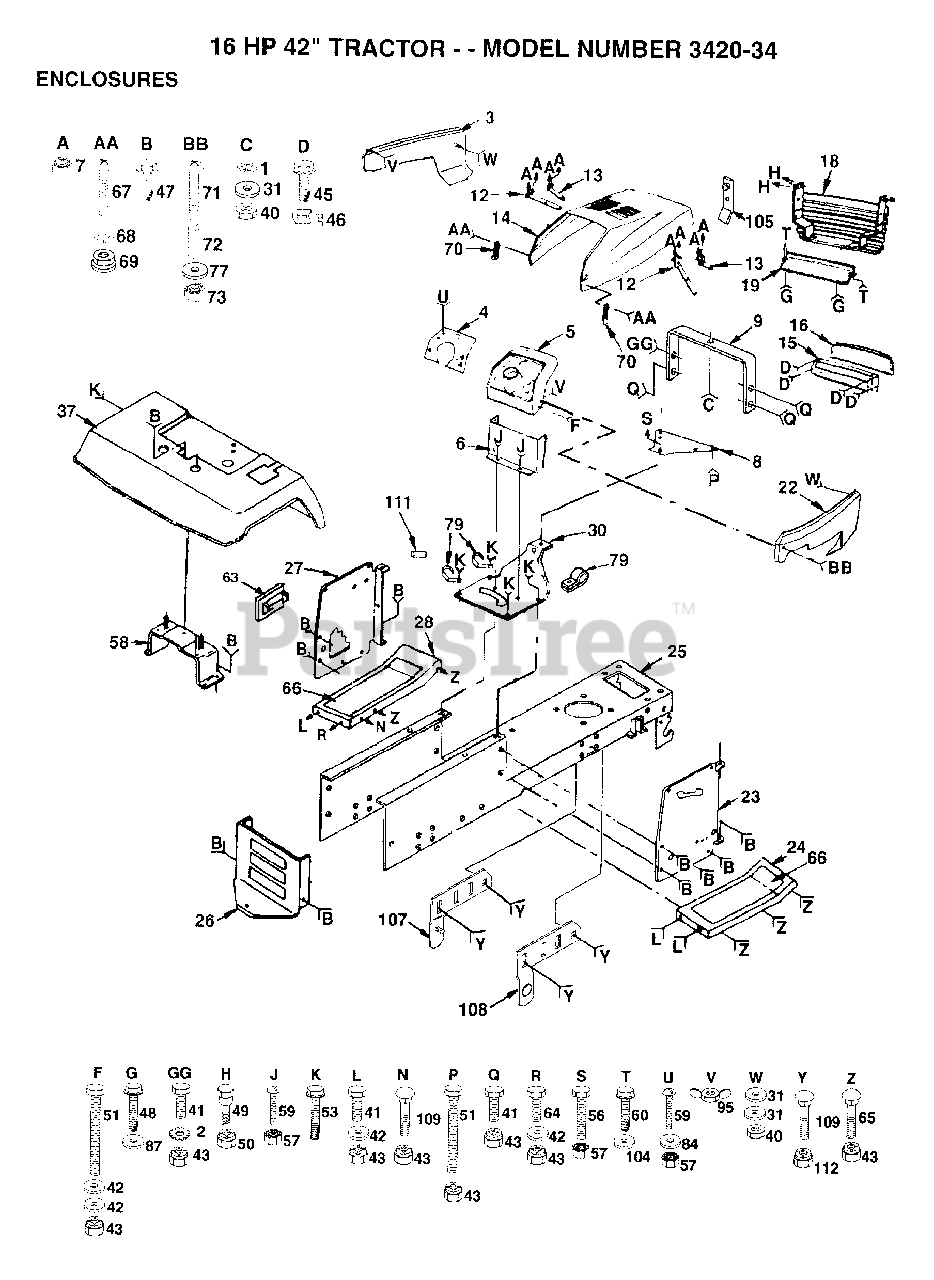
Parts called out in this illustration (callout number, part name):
1	LOCKWASHER
2	LOCKWASHER
3	"PANEL,SIDE LH"
6	DASH ASSY LT
7	NUT
9	SUPPORT ASS'Y
16	LENS LT
27	PANEL.DASH.LH
30	SADDLE.LT.GOOSE
31	WASHER PM
42	WASHER
46	"""J"" FASTENER LT"
47	SCREW
48	SCREW
53	SCREW LT
56	BOLT
58	BRKT FENDER
59	SCREW
60	SCREW HEX CRT
63	COVER ACCESS
65	BOLT
66	FOOTREST PAD
67	SCREW
68	LOCKWASHER
69	WELDNUT
70	HOOD LATCH T
71	SCREW
72	SPACER LT
77	WASHER
79	CLIP T
84	WASHER
87	WASHER
104	WASHER
107	PIVOT BRKT LH
108	PIVOT BRKT RH
112	NUT
